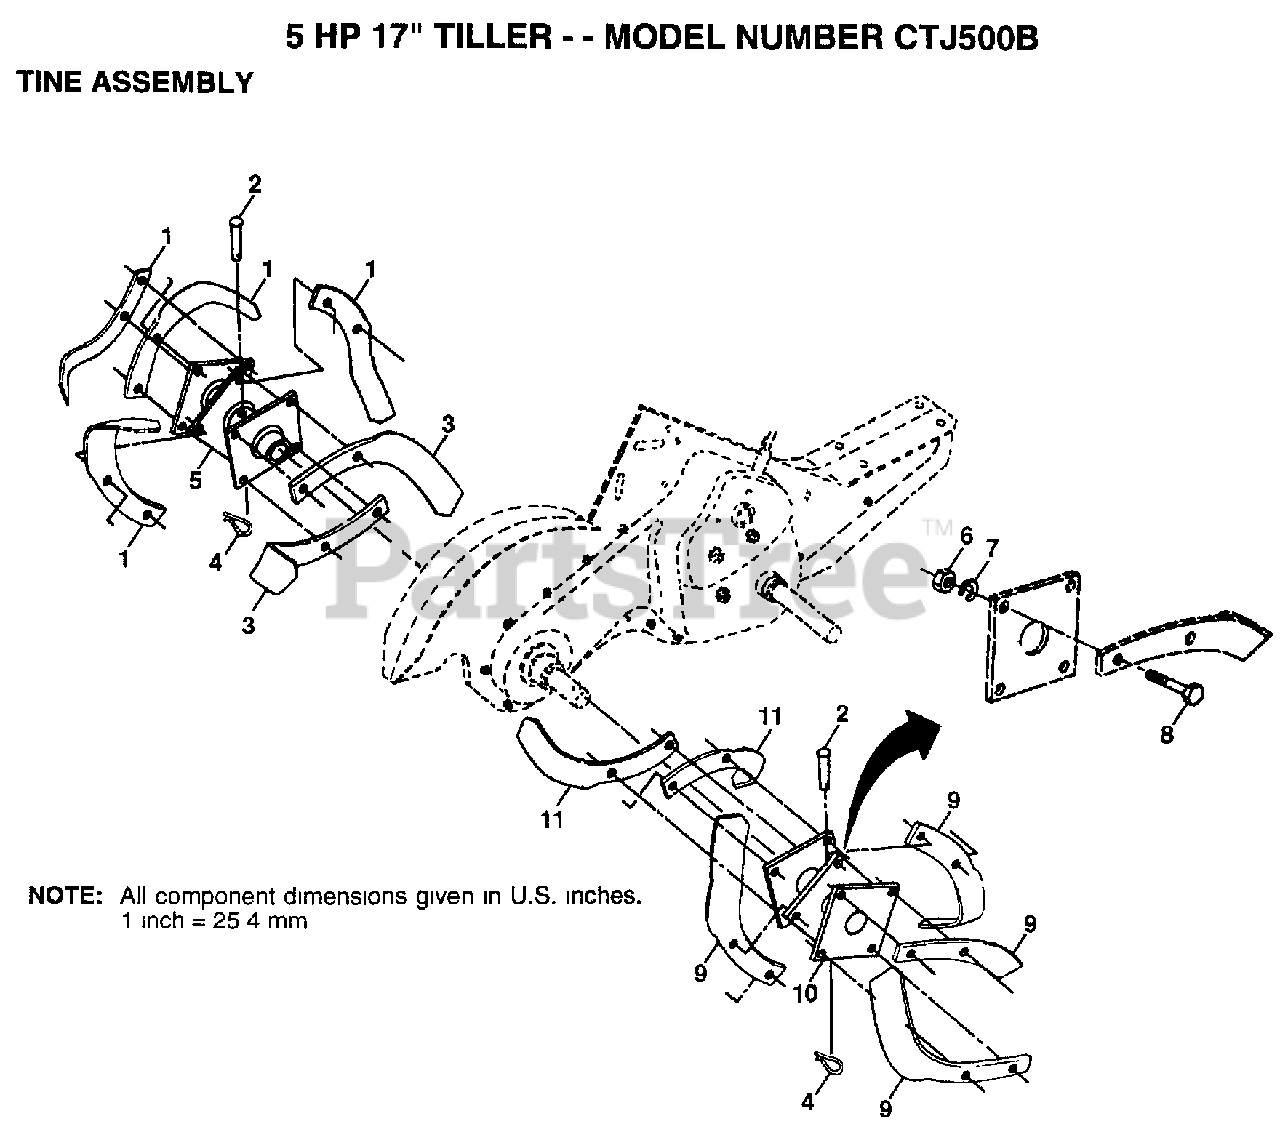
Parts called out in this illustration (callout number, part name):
2	PIN.CLEVIS.SHEAR
3	"TINE.LH.12"""
4	RETAINER.SPRING
5	HUB&PLATE ASM LH
7	LOCKWASHER
8	BOLT
10	HUB&PLATE ASM RH
11	"TINE.RH.12"""
